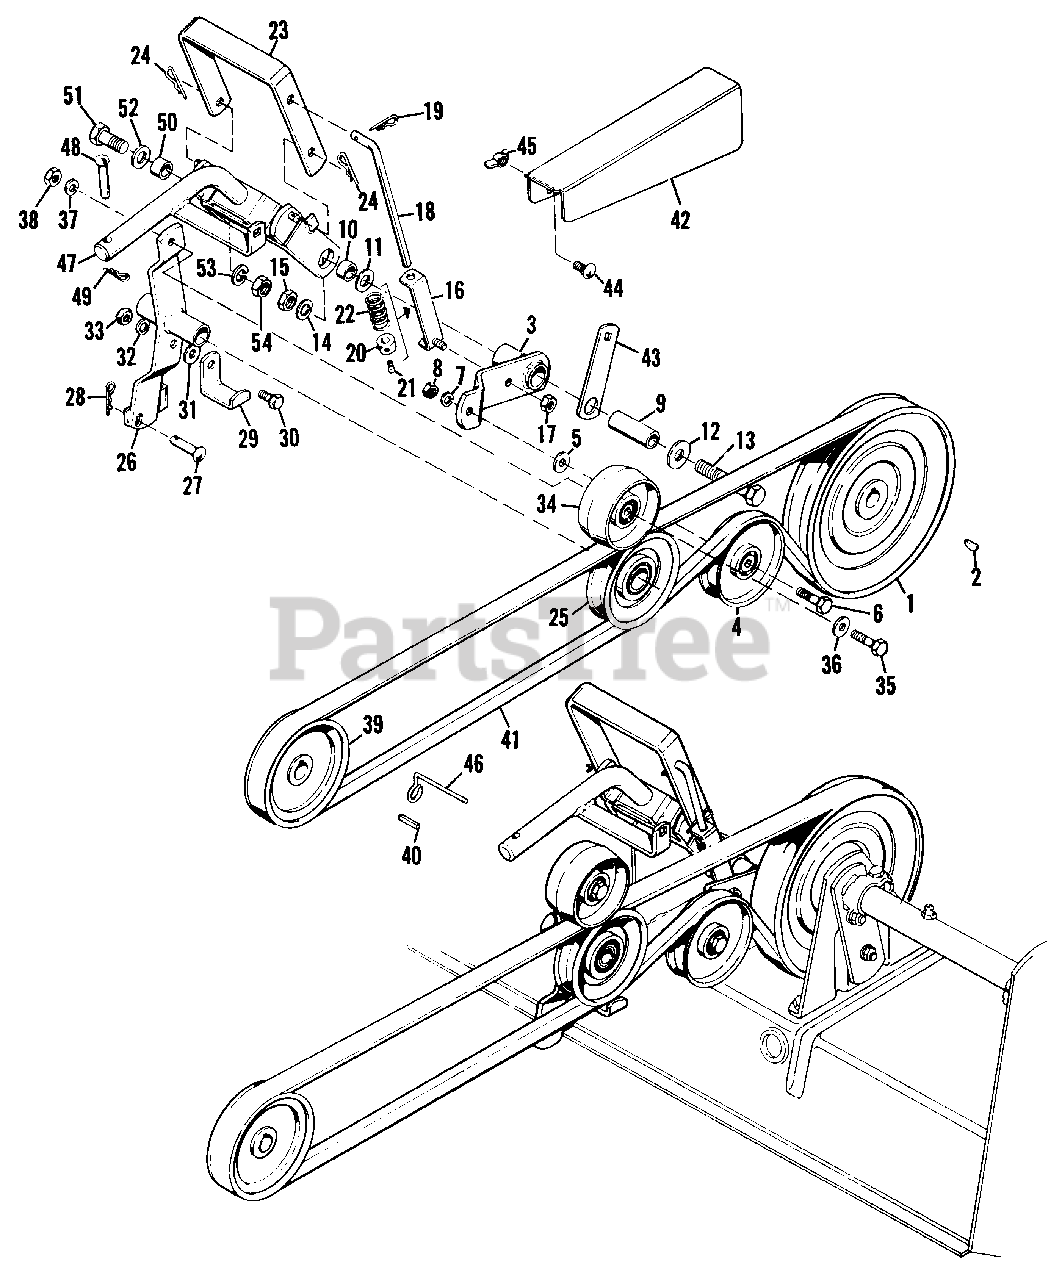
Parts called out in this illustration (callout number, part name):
3	Clutch Lever Assembly
4	Idler Pulley
5	Plain Washer 5/16"
6	Hex Capscrew, 3/8"-16 x 1-1/4" lg.
7	Lock Washer, 3/8"
8	Hex Nut, Full, 3/8"-16
11	Plain Washer, 3/8"
12	Plain Washer, 7/16"
13	Hex Capscrew, 7/16"-14 x 3-1/2" lg.
14	Lock Washer, 7/16"
15	Hex Nut, Jam, 7/16"-14
16	Rod Guide Assembly
17	Hex Nut, Full Lock, 5/16"-18
18	Clutch Rod
19	Spring Clip
21	Sq. Hd. Set Screw, 1/4"-20 x 3/8" lg.
23	Clutch Handle
24	Spring Clip
25	Idler Pulley
26	Idler Arm Assembly
28	Spring Clip
30	Hex Capscrew, 3/8"-16 x 7/8" lg.
31	Plain Washer, 3/8"
32	Lock Washer, 3/8"
33	Hex Nut, Full, 3/8"-16
34	Idler Pulley
35	Hex Capscrew, 3/8"-16 x 1-1/4" lg.
36	Plain Washer, 5/16"
37	Lock Washer, 3/8"
38	Hex Nut, Full, 3/8"-16
39	Drive Pulley
42	Belt Guard
43	Belt Guard Support
44	Carriage Bolt, 5/16"-18 x 3/4" lg.
45	Wing Nut, 5/16"-18
47	Lift Bar Assembly
48	Pin
49	Spring Clip
51	Hex Capscrew, 7/16"-14 x 1-1/4" lg.
52	Plain Washer, 3/8"
53	Lock Washer, 7/16"
54	Hex Nut, Jam, 7/16"-14
